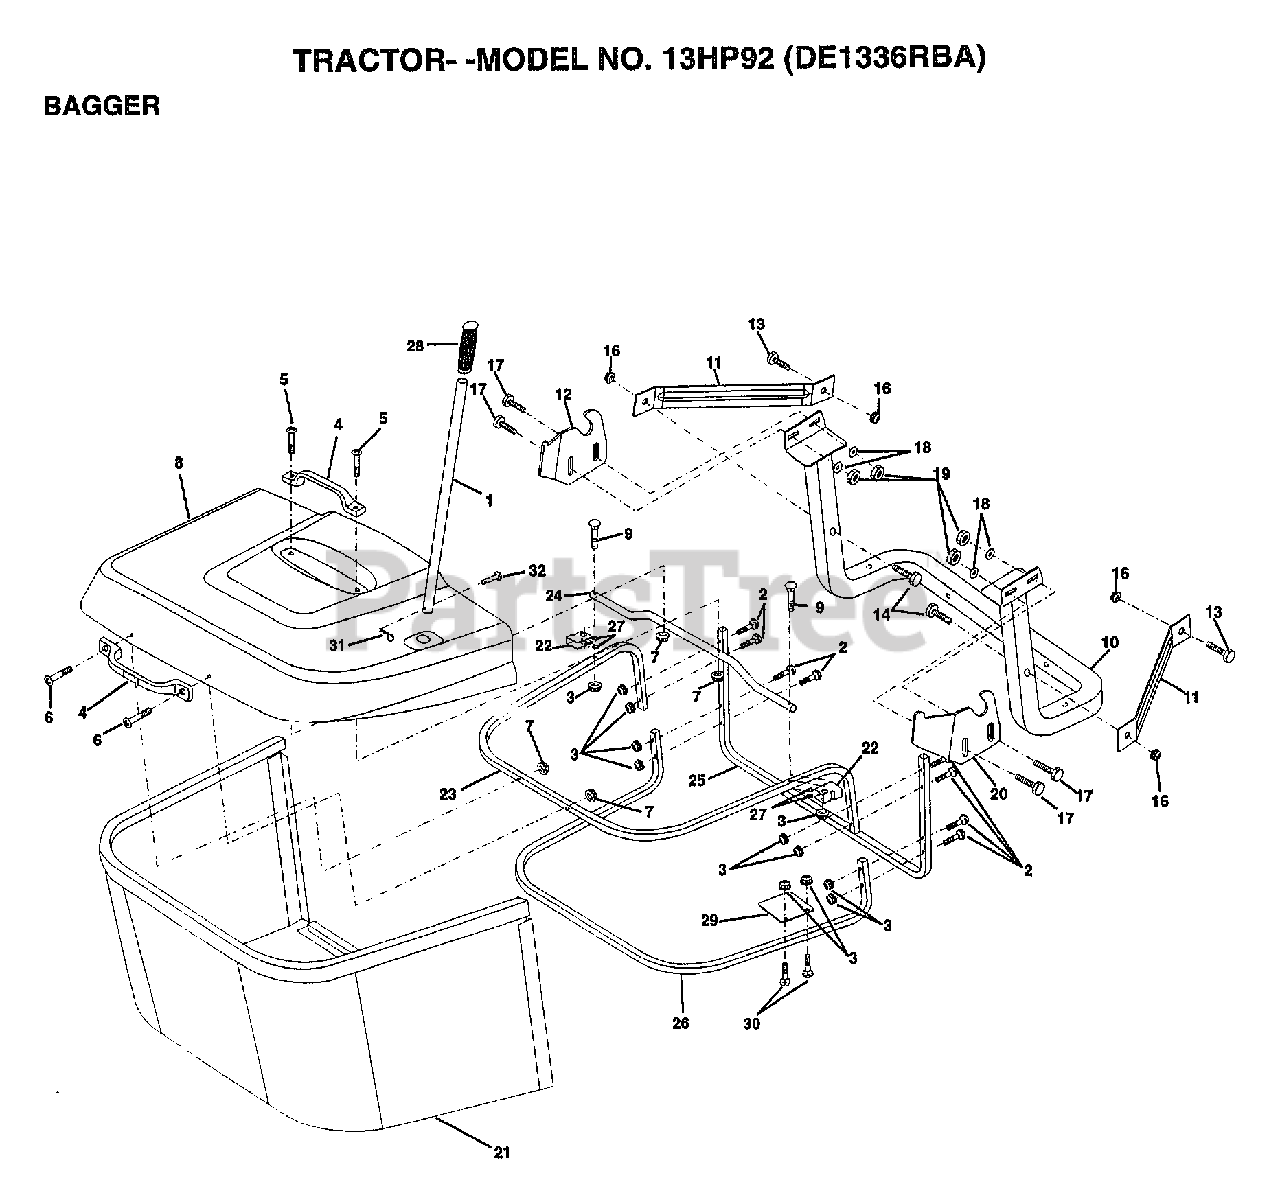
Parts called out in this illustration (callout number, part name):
1	TUBE.HDLE.BAG.CRD
2	BOLT.CARRIAGE.1/4-20X2.0
4	HANDLE.GRAB.BLACK.
5	"SCREW,PAN.HEAD"
8	COVER.BAGGER.CRD
9	BOLT CARRIAGE
10	SUPT.ASM.WLDMNT.BAG.CRD
11	BRKT.SUPT.UPPER.BAG.CRD
12	BRKT.PIVOT.BAG.LH.CRD
13	BOLT
14	BOLT.HEX.3/8-16X2-1/2
17	BOLT
18	WASHER
19	NUT
20	"BRKT.PIVOT.BAG,RH.CRD"
21	BAG.ASM.CRD
22	BRKT.SIDE.BAG.CRD
23	TUBE.UPPER.BAG.CRD
24	TUBE.PIVOT.BAG.CRD
25	TUBE.FT.BAG.CRD
26	TUBE.LOWER.BAG.CRD.
27	GROMMET.EXTRUDED
28	GRIP.HANDLE.BLACK
29	PLATE.STOP.BAG.HDLE.CRD
30	BOLT.CARRIAGE
31	RETAINER M
32	RIVET.DRILL.1.75
